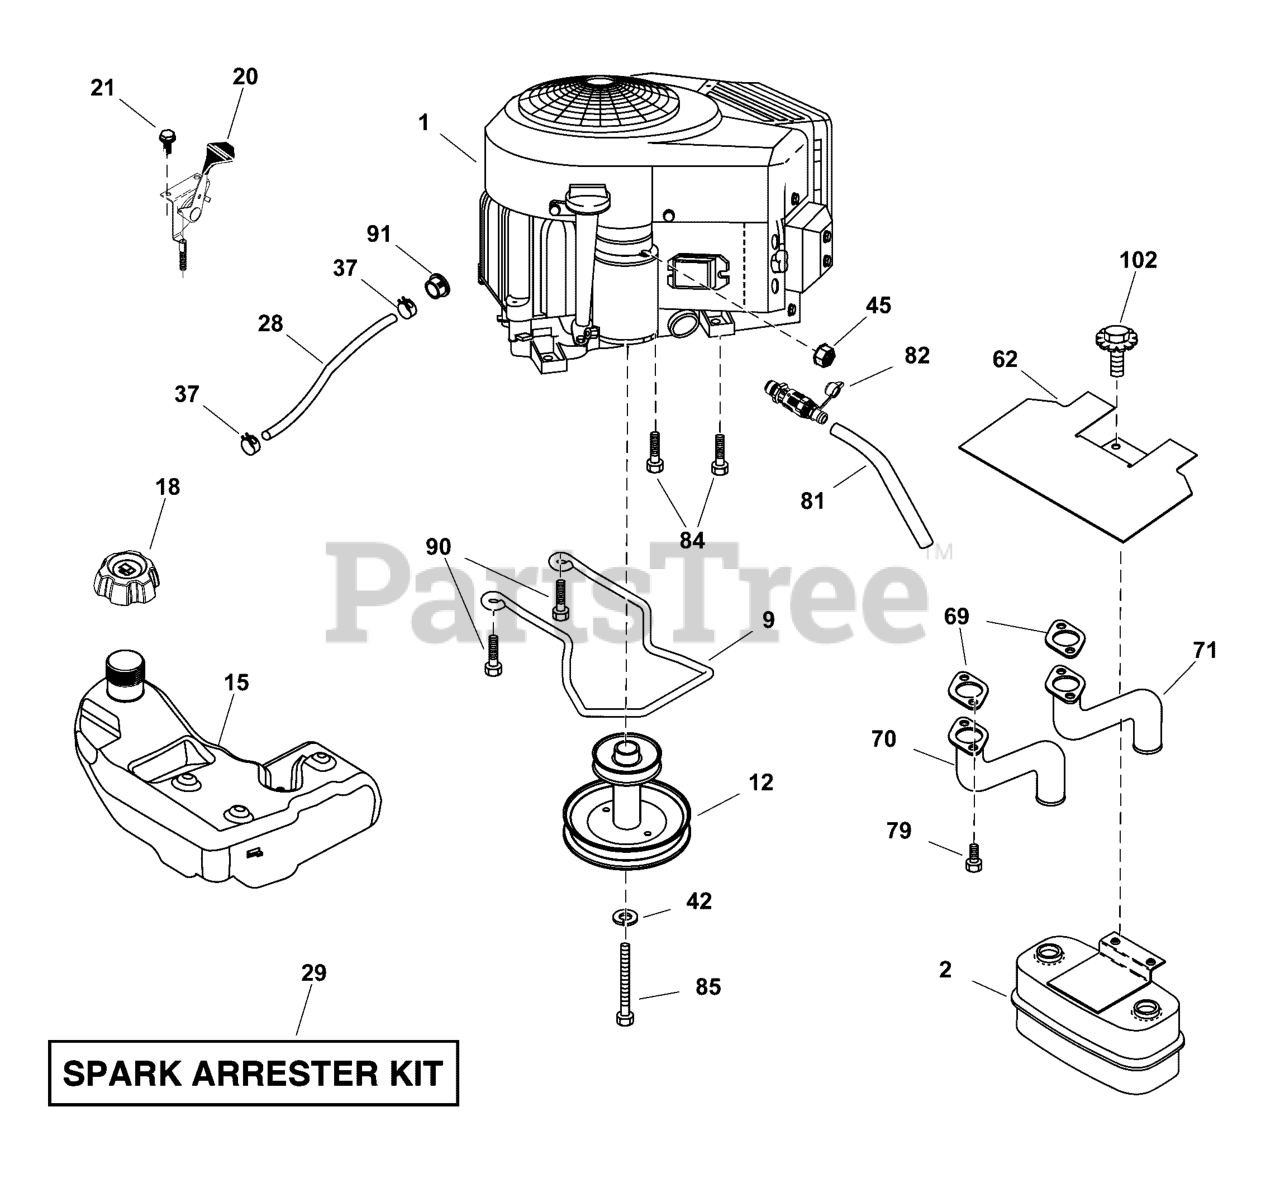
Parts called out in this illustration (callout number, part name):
1	Engine B&S Model No. 44N877-0003-G1
9	KEEPER, Engine Belt
12	PULLEY, Engine
15	TANK, Fuel
18	CAP, Fuel
20	CONTROL, Throttle/Choke
21	Screw #10 x 0.750 BOS Thread
28	Fuel Line
29	Spark Arrester Kit
37	Clamp Hose
42	WASHER, 7/16 Lock SLW
45	Nut Keps Hex 1/4-20 unc
62	Shield Heat Muffler
70	Exhaust Tube LH
71	Exhaust Tube RH
79	Screw Socket HD 5/16-18 x 1
81	Tube Drain Oil Easy
82	Valve Oil Drain
84	Screw 3/8-16 x 1-1/4
85	BOLT, 7/16-20 X 4 X GR. 5-1.5, Hex
90	Screw Hexwsh Thd 3/8-16 x 1
91	Bushing
102	Screw 5/16-18 X 3/4 Smgml Tap/Bl
